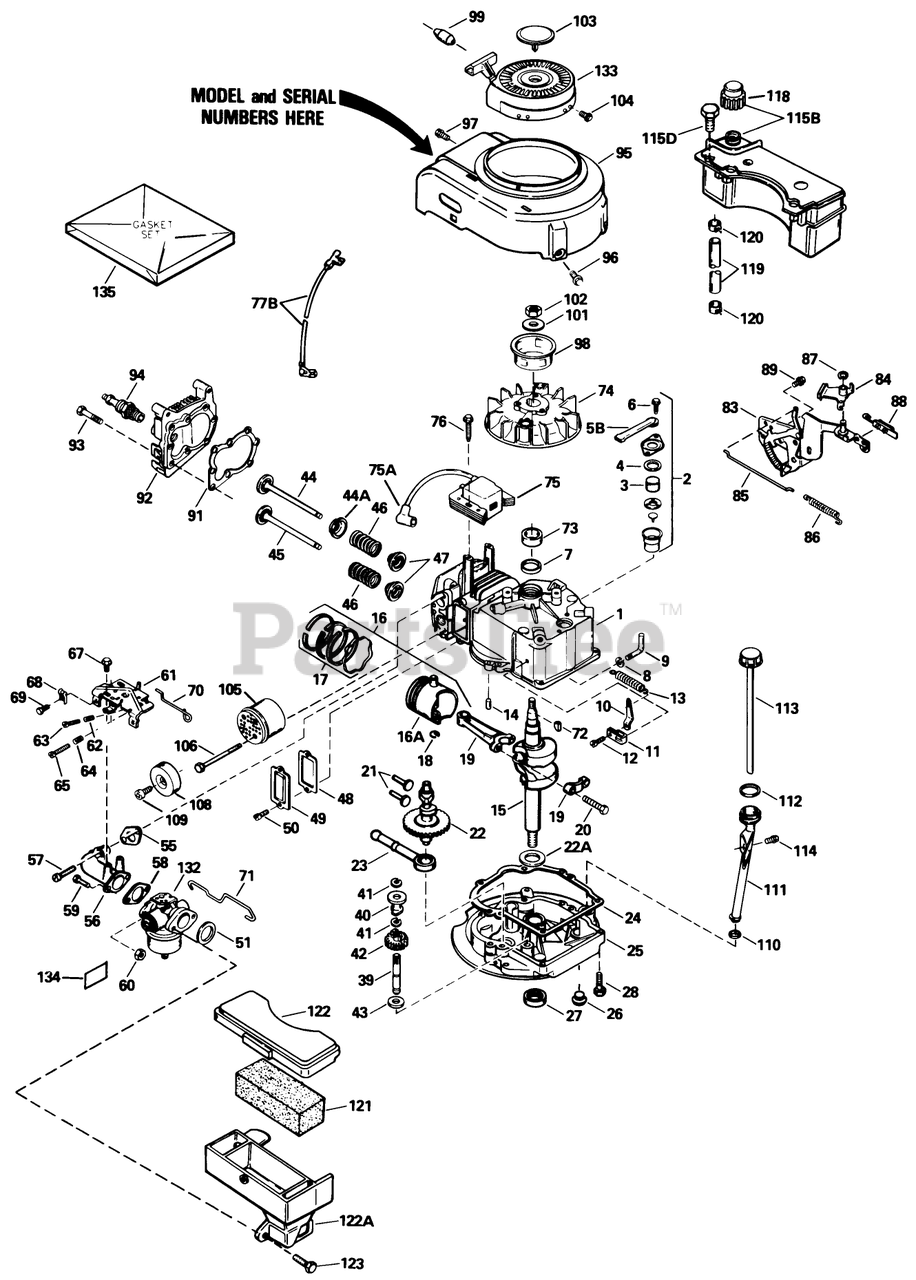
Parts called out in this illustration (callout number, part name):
1	Cylinder Assy. (Incl. #24)
2	Breather Assy. (Incl. Ref. #46 thru 51)
3	Element-Breather
4	Gasket-Breather
5B	Tube, Breaker
6	Screw (10-24 x 9/16)
7	Seal-Oil
8	Washer-Flat
9	Rod, Governor (Incl. No. 36)
10	Governor Lever
11	Clamp-Lever, Governor
12	Screw
13	Spring Governor
14	Pin-Dowel
15	Crankshaft
16	Piston-Pin Ring Assy. (Std.)(Incl. Ref. #16A, 17 18)
16	Piston-Pin Ring Assembly (.010 oversize)(Incl. Ref. #16A, 17 18)
16	Piston, Pin Ring Assy. (.020 Oversize)(Incl. Ref. #13A, 14, 15)
16A	Piston Pin Assy. (Std.)(Incl. Ref. #14)
16A	Piston Pin Assembly (.010 oversize)(Incl. Ref. #18)
16A	Piston Pin Assy. (.020 Oversize) (Incl. Ref. #14)
17	Ring Set-Piston (Std.)
17	Ring Set, Piston(.0100versize)
17	Ring Set (.020" OS)
18	Ring-Retaining, Piston Pin
19	Rod Assy., Connecting (Incl. Ref. #17)
20	Bolt-Rod, Connecting
21	Lifter-Valve
22	Camshaft(Mech.Comp. Release)
22A	Washer-Thrust
23	Oil Pump ASM
24	Gasket
25	Flange-Mounting (Incl. Ref. #26, 27 39)
26	Plug Oil Drain
27	Seal-Oil
28	Screw (1/4-20 x 1-1/4)
39	Shaft-Governor
40	Spool-Governor
41	Ring-Retaining
42	Governor Gear ASM
43	Washer
44	Valve, Intake (Std.) (Incl. Ref. #40)
44	Valve, Intake (1/32" oversize)(Incl. No. 40)
44A	Seal Assy., Intake
45	Valve, Exhaust (Std.)(Incl. No. 40)
45	Valve, Intake (1/32" oversize)(Incl. No. 40)
46	Spring-Valve
47	Cap-Valve, Spring
48	Gasket-Cover, Valve
49	Cover-Valve
50	Screw
51	Gasket-Cleaner, Air
55	Gasket-Intake Pipe
56	Pipe-Intake (Incl. Ref. #59)
57	Screw (1/4-20 x 1)
58	Gasket
60	Nut and Lock Washer (1/4-28)
61	Control Assy.-Remote Speed (Incl. Ref. #69 thru 72 76)
62	61709/GIL1515A/95-5
63	Screw
64	Spring-Compression
65	Screw
67	Screw (10-24 x 9/16)
68	Conduit
69	Screw (10-32 x 3/8)
70	2035A67 ADD.ASSEMBL
71	Link-Throttle
72	Key-Flywheel
73	Spacer
74	Flywheel
75	Solid State
75A	Cover-Spark Plug
76	Screw
77B	Ground Wire
83	Bracket-S.E. Brake
84	Lever-Brake
85	Link-Control
86	Spring-Extension
87	Ring-Retaining
88	Terminal
89	Screw (1/4-20 x 3/8)
91	Gasket-Cylinder Head
92	Head-Cylinder
93	Screw (5/16-18x1-1/2)
94	Spark Plug-Resistor (R J19 L M)
95	Housing-Blower
96	Screw (1/4-20 x 1/2)
97	Screw (10-24 x 9/16)
98	Hub-Starter
99	Retainer-Starter Rope
101	Washer-Belleville
102	Nut-Flywheel
103	Plug Starter
104	Screw, Hex Hd.
105	Muffler (Incl. Ref. #122)
106	Screw
108	Cover-Muffler
109	Screw (8-32 x 3/8)
110	Gasket
111	Oil Fill Tube
112	O-Ring
113	Dipstick
114	Screw (10-32 x 1/2)
115B	Tank Assembly-Fuel (Incl. Ref. #102)
115D	Screw (10-32 x 35/64)
118	Cap-Fuel
119	Line-Fuel
120	Clamp-Line, Fuel
121	Filter-Air Cleaner
122	Cover-Air Cleaner
122A	Body Air cleaner
123	Screw
132	Carburetor (Incl. Ref. #83)
133	Starter-Rewind
134	Decal-Primer
135	Gasket Set (Incl. Items Marked *)
